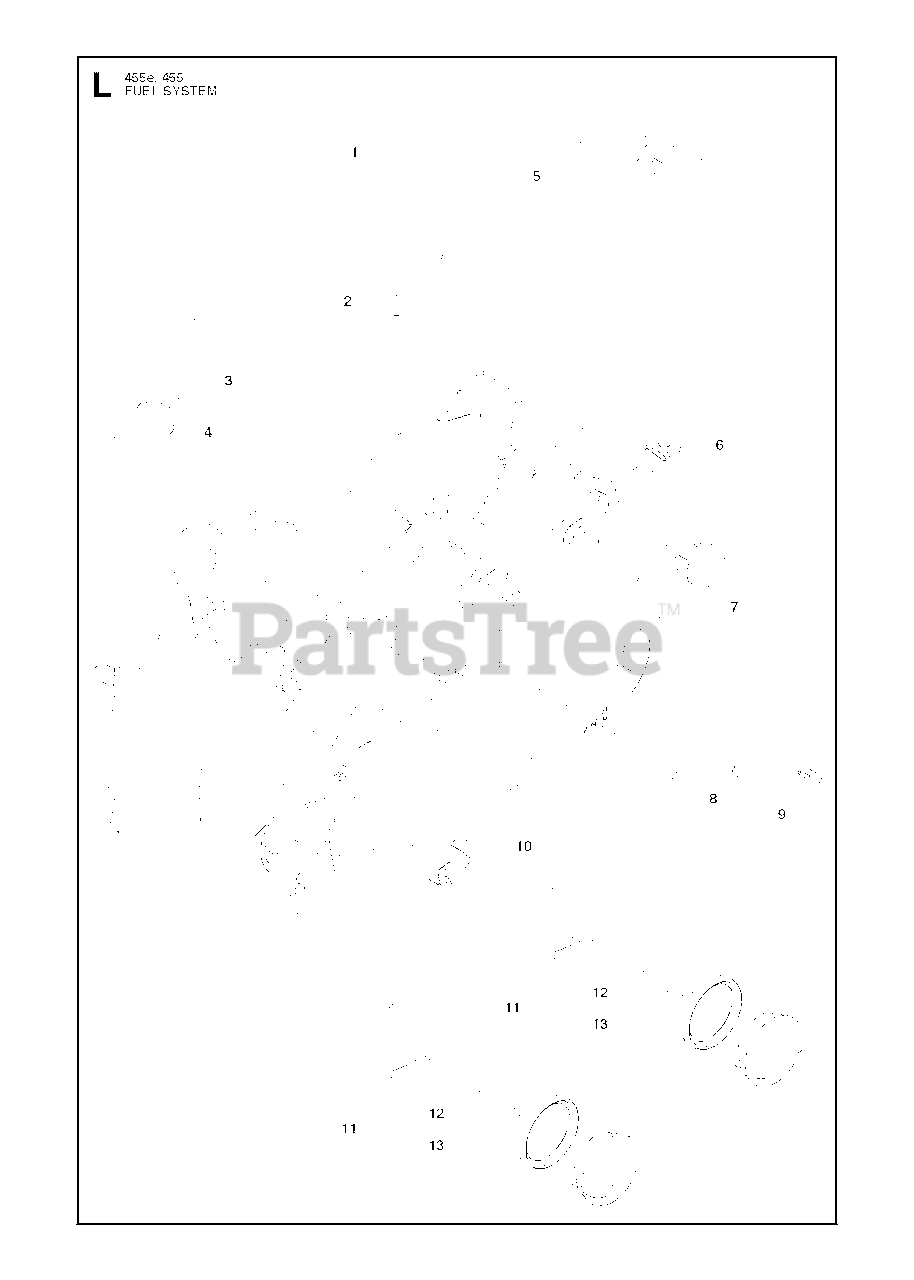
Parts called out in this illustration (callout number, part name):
2	FUEL TANK BUSHING
3	FUEL HOSE
4	FUEL FILTER
5	FUEL HOSE/38MM
7	AIR PURGE BUBBLE
10	SWITCH PLATE
11	TANK CAP
